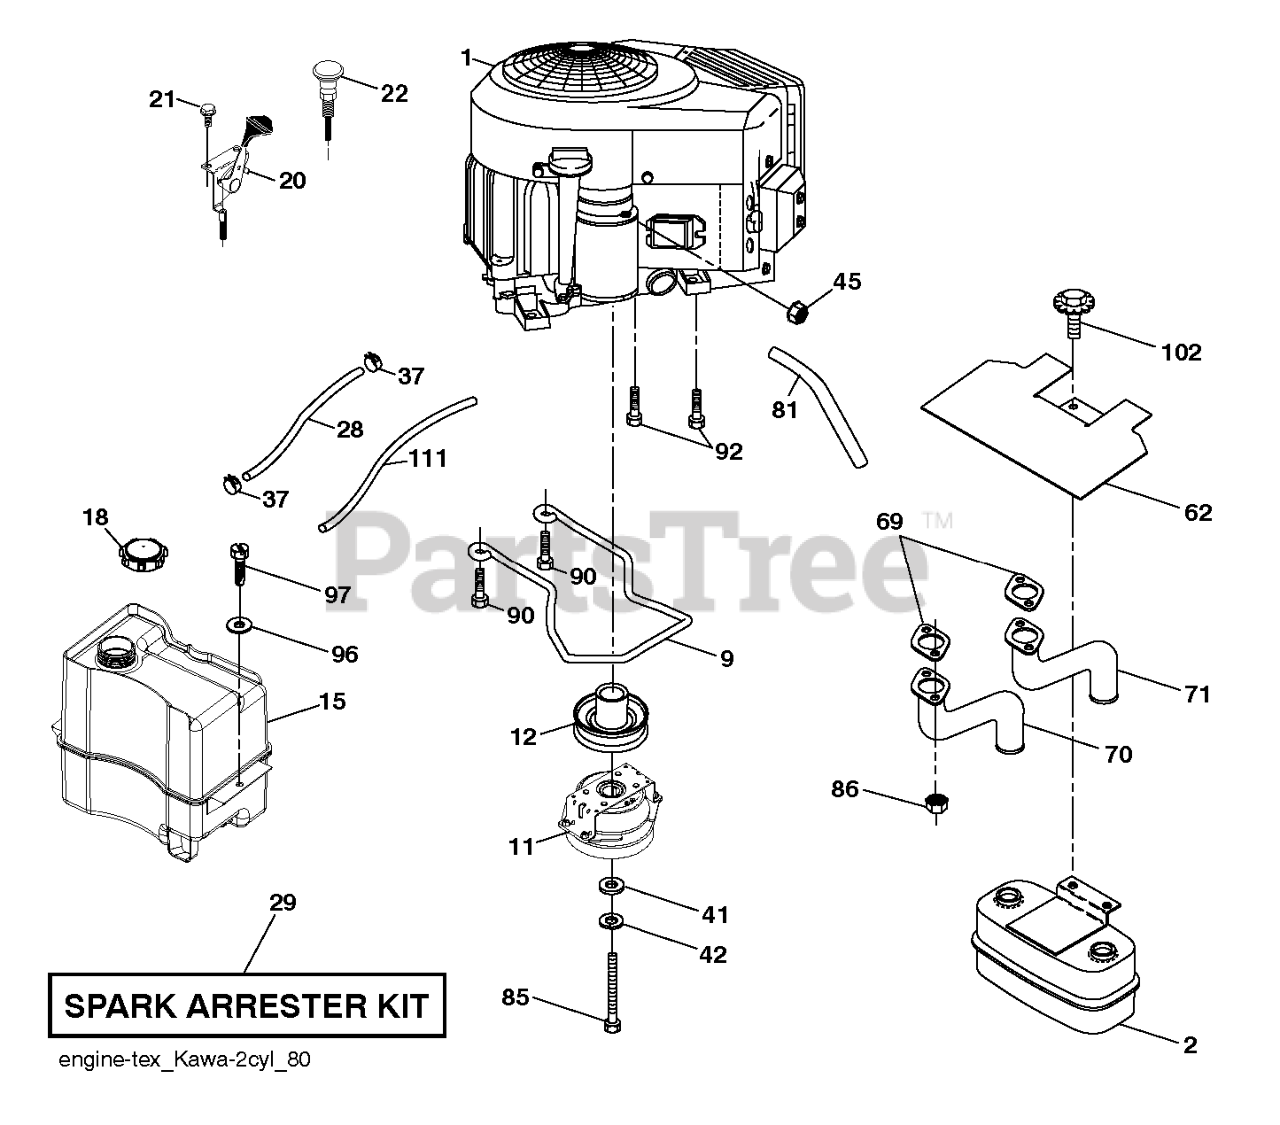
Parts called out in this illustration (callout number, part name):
2	MUFFLER.ASM.TWIN.MNTG.BRACKET
11	CLUTCH.OGURA.5.0PD.GT1.5A-EH07
12	PULLEY.ENGINE.TUFFTORQ
18	FUEL.CAP.ASM.2.25TETHRED.RATCH
20	CONTROL.THROTTLE.COBRA.BLACK
22	CONTROL, CHOKE
28	HOSE.1/4".LOW.PERM.FUEL.LN.60"
29	KIT.SPARK ARRESTOR 794945 B&S
37	HOSE CLAMP
62	SHIELD.HEAT.MUFFLER
70	TUBE.EXHAUST.LH.FR961/FR730
71	TUBE.EXHAUST.RH.FR961/FR730
81	TUBE, DRAIN OIL ASM.
85	BOLT.HEX.7/16-20X3.75.GR5.RED
86	NUT.HEX.FLANGE.TOPLOCK
90	SCREW 3/8-16X1
92	SCREW 3/8-16X1
97	SCREW HEXWSHR 1/4-20X3/4
102	SCREW
111	TUBE.PURGE.FUEL.1875
